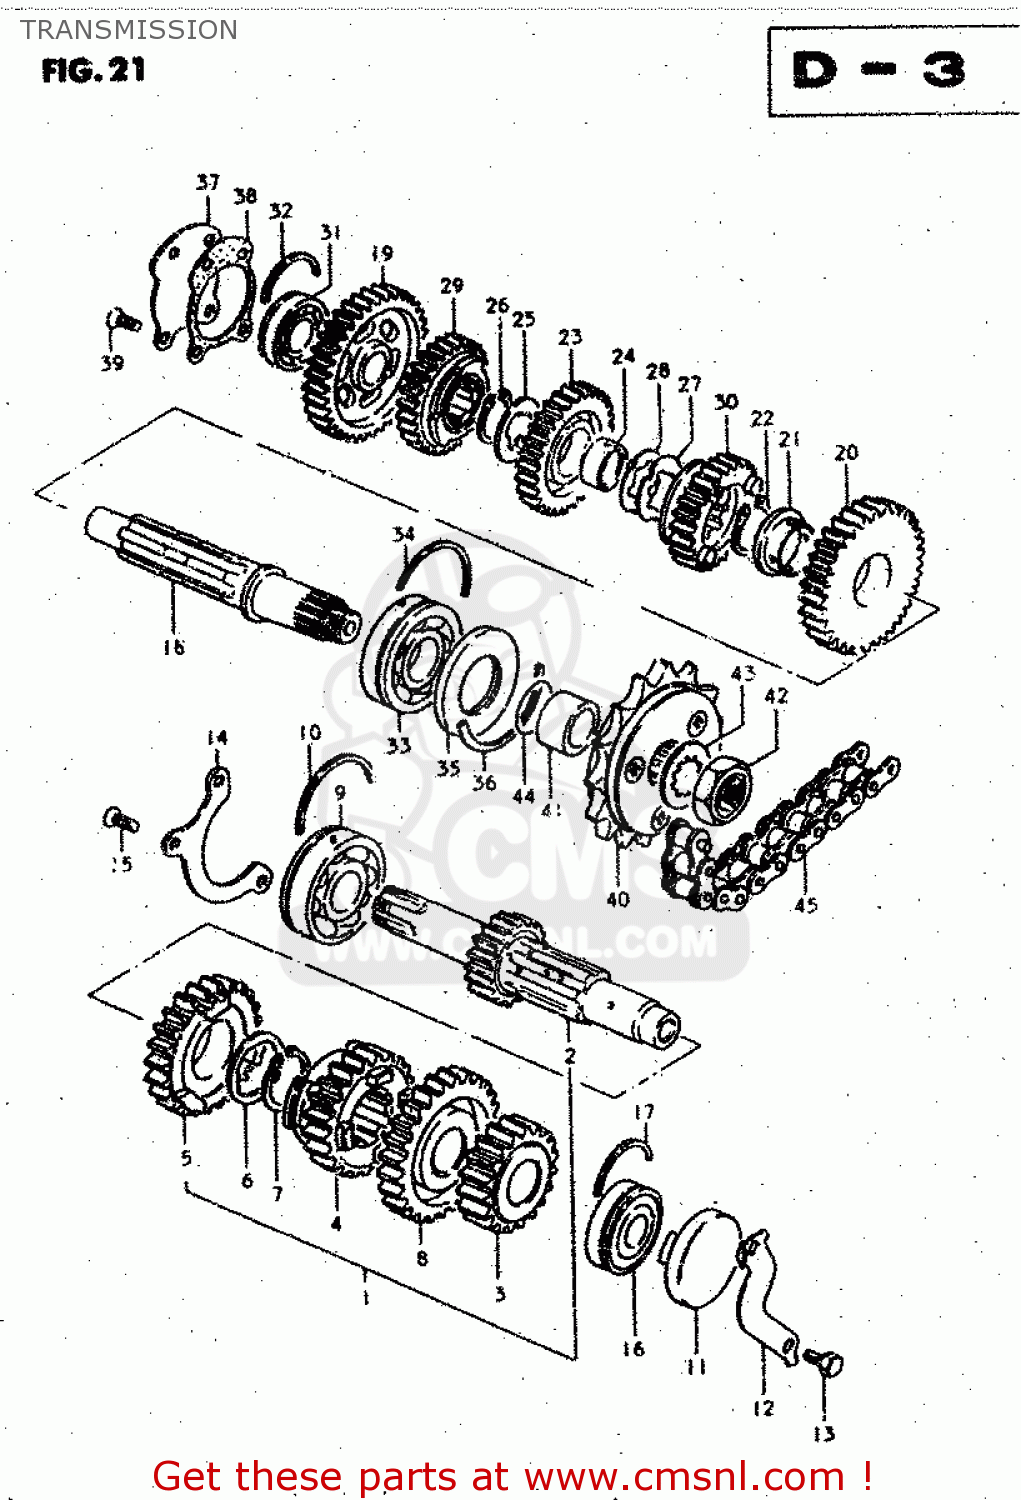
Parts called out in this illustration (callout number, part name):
1	SHAFT ASSEMBLY,COUNTER
2	SHAFT,COUNTER
3	GEAR,SECOND DRIVE
4	GEAR,THIRD DRIVE
5	GEAR,FOURTH DRIVE
6	WASHER,LOCK
7	CIRCLIP
8	GEAR,FIFTH DRIVE
9	BEARING(25X62X17)
10	C-RING
11	PLUG
12	RETAINER,CL PUSH ROD OIL SEAL
13	BOLT
14	RETAINER,CNTR SHAFT BEARING
15	SCREW
16	BEARING(20X47X14)
17	C RING
18	SHAFT,DRIVE
19	GEAR,FIRST DRIVEN
20	GEAR,SECOND DRIVEN
21	BUSH(28X32X2)
22	CIRCLIP
23	GEAR,THIRD DRIVEN
24	BUSH,3RD DRIVEN GEAR
25	WASHER,LOCK
26	CIRCLIP
27	WASHER,LOCK
28	WASHER
29	GEAR,FOURTH DRIVEN
30	GEAR,FIFTH DRIVEN
31	BEARING
32	C RING
33	BEARING(25X62X17)
34	C-RING
35	SEAL,OIL(32X62X7)
36	C RING
37	PLATE,DRIVE SHAFT
38	GASKET,DRIVESHAFT PLATE (MCA)
39	SCREW
40	SPROCKET,ENGINE
41	SPACER(25X32X18.6)
42	NUT
43	WASHER
44	O RING(D:1,ID:24.5)
45	CHAIN ASSEMBLY,DRIVE
